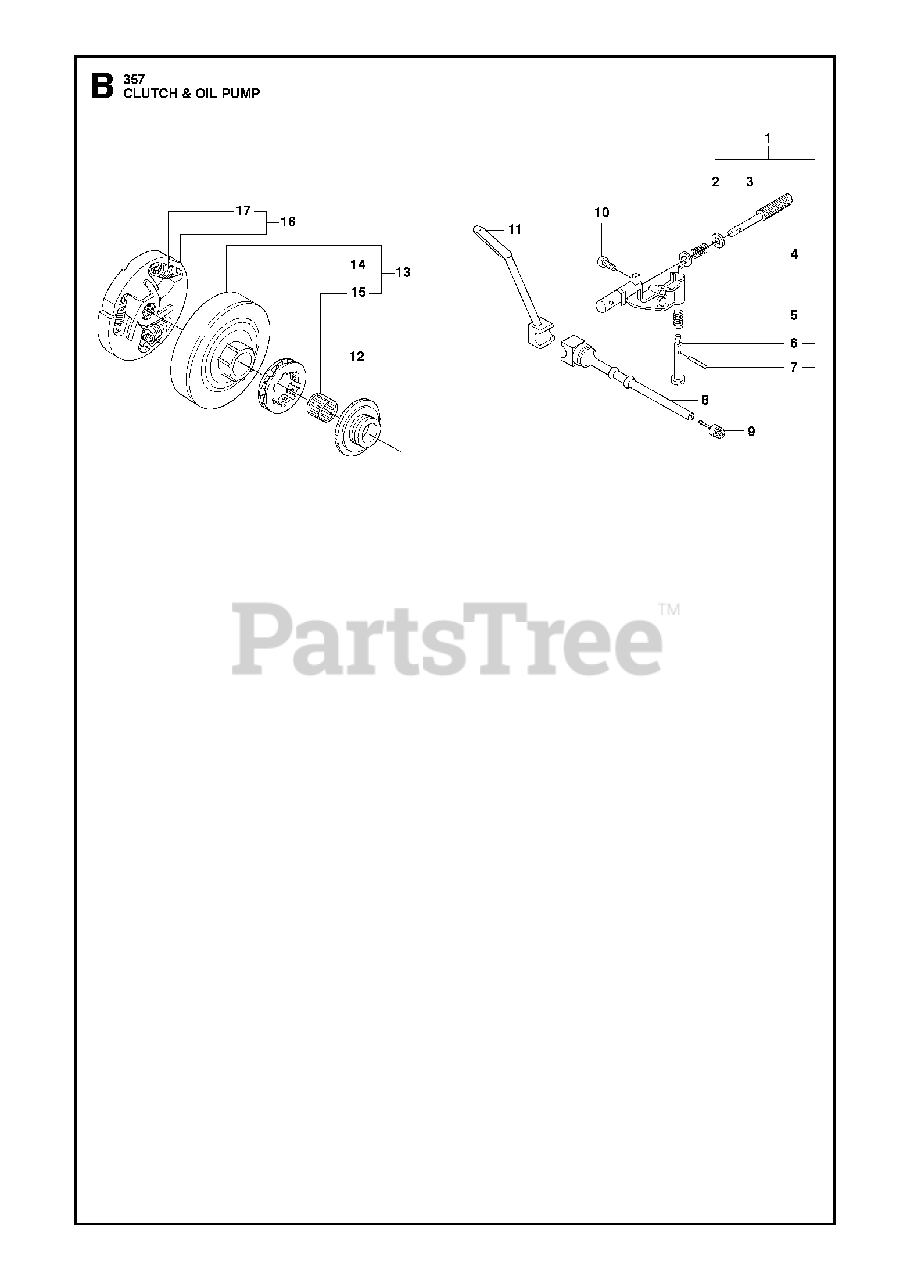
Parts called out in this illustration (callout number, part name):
1	OIL PUMP ASSY
2	WASHER
3	PUMP PISTON
4	SPRING
5	SPRING
6	ADJUSTER
7	PIN
8	RP HOSE
9	OIL PLUMMET
12	PUMP GEAR
13	CLUTCH DRUM
14	RIM SPROCKET 7T .325
14	68210 RIMSPROCKET
15	NEEDLE BEARING
16	CLUTCH
17	SPRING
